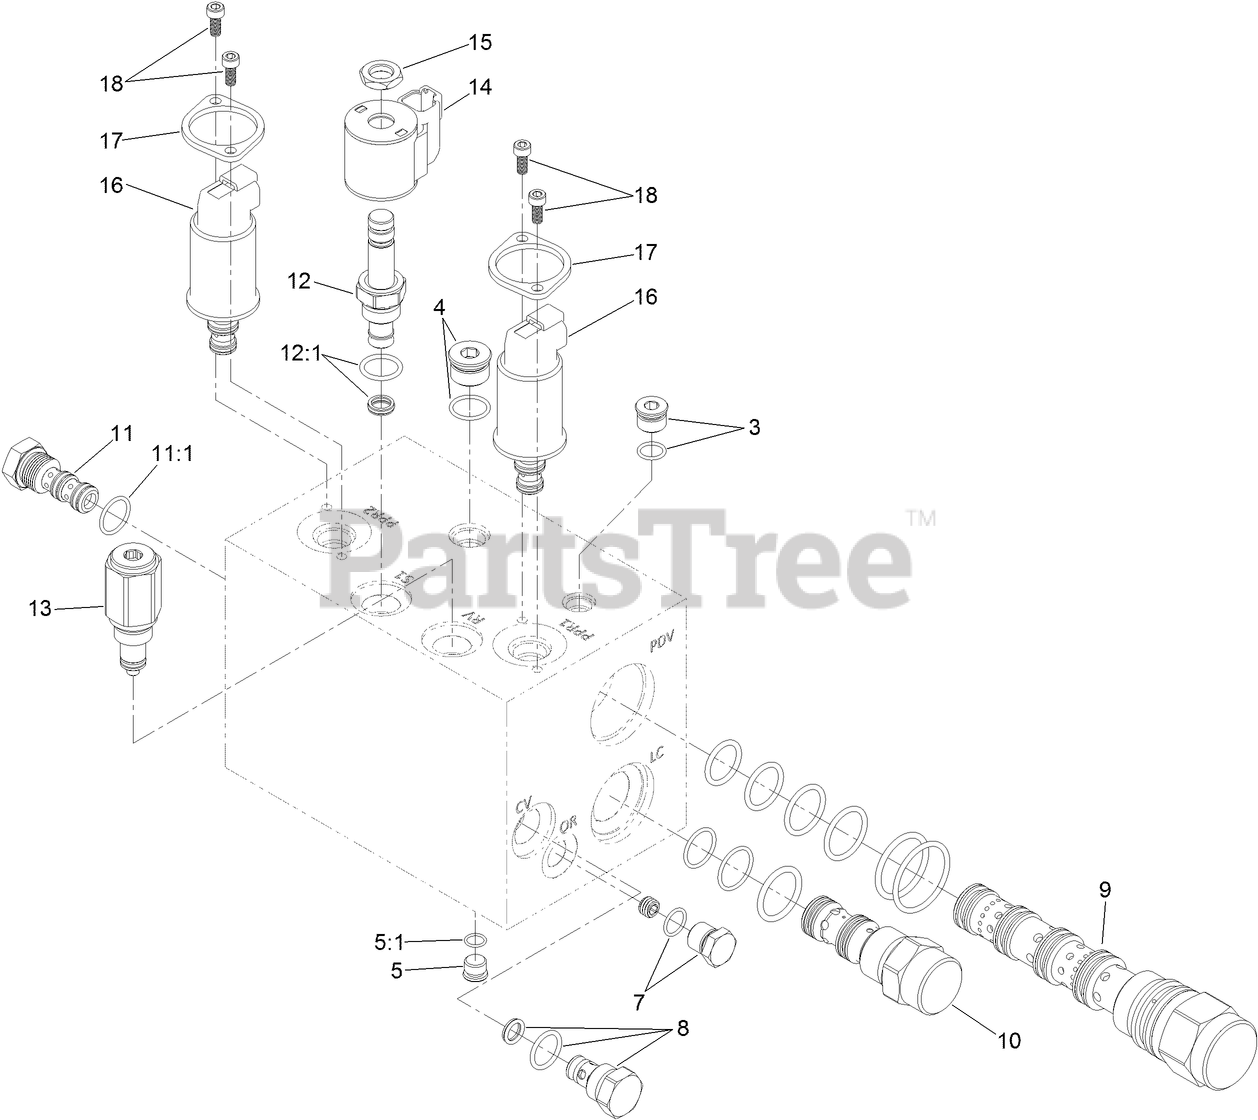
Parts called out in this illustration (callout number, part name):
1	BLOCK-MANIFOLD
2	Plug-Expander
4	PLUG-HYD
5	PLUG ASM
5:1	O-RING
8	VALVE-CHECK,
9	VALVE-PROPORTIONAL, DIRECTIONAL
10	CARTRIDGE-LOGIC,
11	SHUTTLE-LOAD
11:1	SEAL KIT
12	VALVE-SOLENOID
12:1	SEAL KIT
13	VALVE-RELIEF
14	E COIL-12V DC
15	NUT-COIL
16	VALVE-PROP PRESS REDUCING/RELIEVING
17	PLATE-MOUNTING, STANDARD
